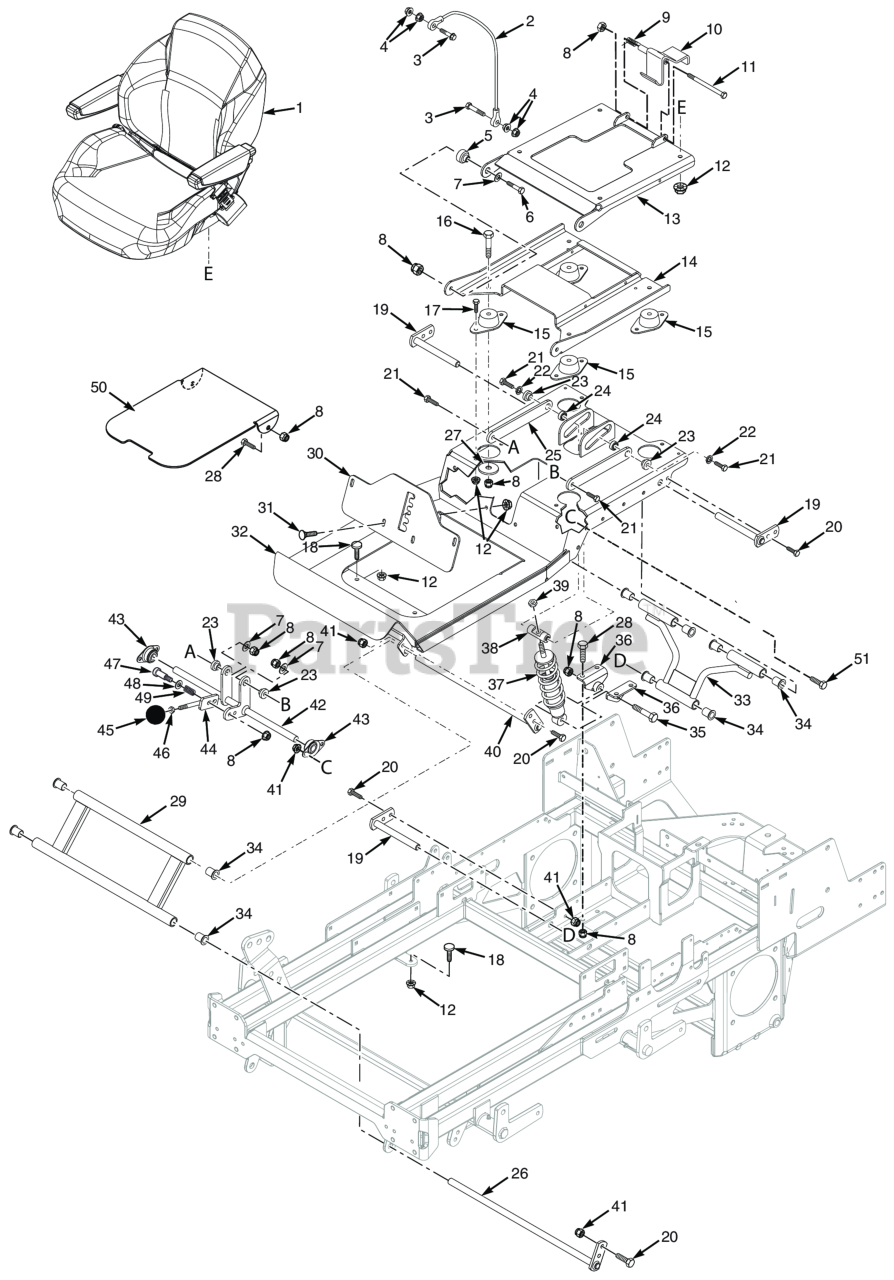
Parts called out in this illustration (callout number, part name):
1	Seat Assembly (INCL 14)
2	Cable, Seat Stop
3	SERR. FLG. HEX HEAD CAPSCREW, 5/16-18 X 3/4
4	NUT, 1/4-20 SERRATED FLANGE HEX HEAD
5	Sleeve, Seat Base Mounting
6	Capscrew, Hex Head 3/8-16 x 2.0"
7	Flatwasher, 3/8" Special (.391 x .938 x .105)
8	HEX NUT, ELASTIC STOP LOCK, 3/8-16
9	Spring, Seat Latch
10	Latch Weldment, Seat
11	Bolt, 3/8-16 x 6.00" Hex Head
12	Nut, Serrated Flange 5/16-18 (Right Front Engine Mounting, Briggs and Kohler Only)
13	Seat Plate Weldment
14	Seat Mounting Plate Weldment w/Decal
15	Isolator, Seat
16	Bolt, Hex Head 3/8-16 x 2-1/4" - 61"
17	BOLT, SERRATED FLANGE HEX HEAD 5/16-18 X 3/4"
18	Bumper, Rubber
19	Shaft Weldment, Rear Op. Platform Pivot
20	Bolt, Heax Head 5/16-18 x 1" (48V / 52V)
21	Bolt, Hex Head, 3/8-16 x 1-1/2"
22	Lockwasher, 3/8" Spring, Kawasaki FX / FS
23	BUSHING, SPEED ADJUSTMENT LEVER
24	Bearing
25	Link, Suspension Seat Tensioner
26	Pin Weldment, Op Platform Lower Pivot
27	Flatwasher, 3/8-.406 x 2.25" x .1875
28	Bolt, Hex Head, 3/8-16 x 1 Gr. 5
29	Suspension Pivot Assembly, Front
30	Bracket, Suspension Adjustment w/Decal
31	Bolt, Carriage 5/16-18x1" (large frame units only)
32	Seat Mounting Base Weldment w/Decal
33	Suspension Pivot Assembly, Rear
34	Bearing, .625 ID Plastic
35	Capscrew, Hex Head 3/8-16 x 2.75"
36	Mount Weldment, Shock
37	Shock Absorber, Suspension
38	Mount, Suspension Shock
39	Nut, Elastic Stop 3/8-16, grade 8 black
40	Pin Weldment, Op Platform Upper Pivot
41	HEX NUT, ELASTIC STOP LOCK, 5/16-18
42	Pivot Weldment, Suspension Tensioner
43	Bearing, Self Aligning - 5/8 I.D.
44	Adjustment Lever, Suspension
45	Knob, OCDC Lever
46	HEX NUT, JAM 3/8-16
47	Bolt, Shoulder 3/8 x 1"
48	Flatwasher, 3/8 (.406 x .812 x .065)
49	Spring, Speed Control Slide
50	Cover, Foot Plate
51	BOLT, SERRATED FLANGE HEX HEAD 5/16-18 X 3/4"
